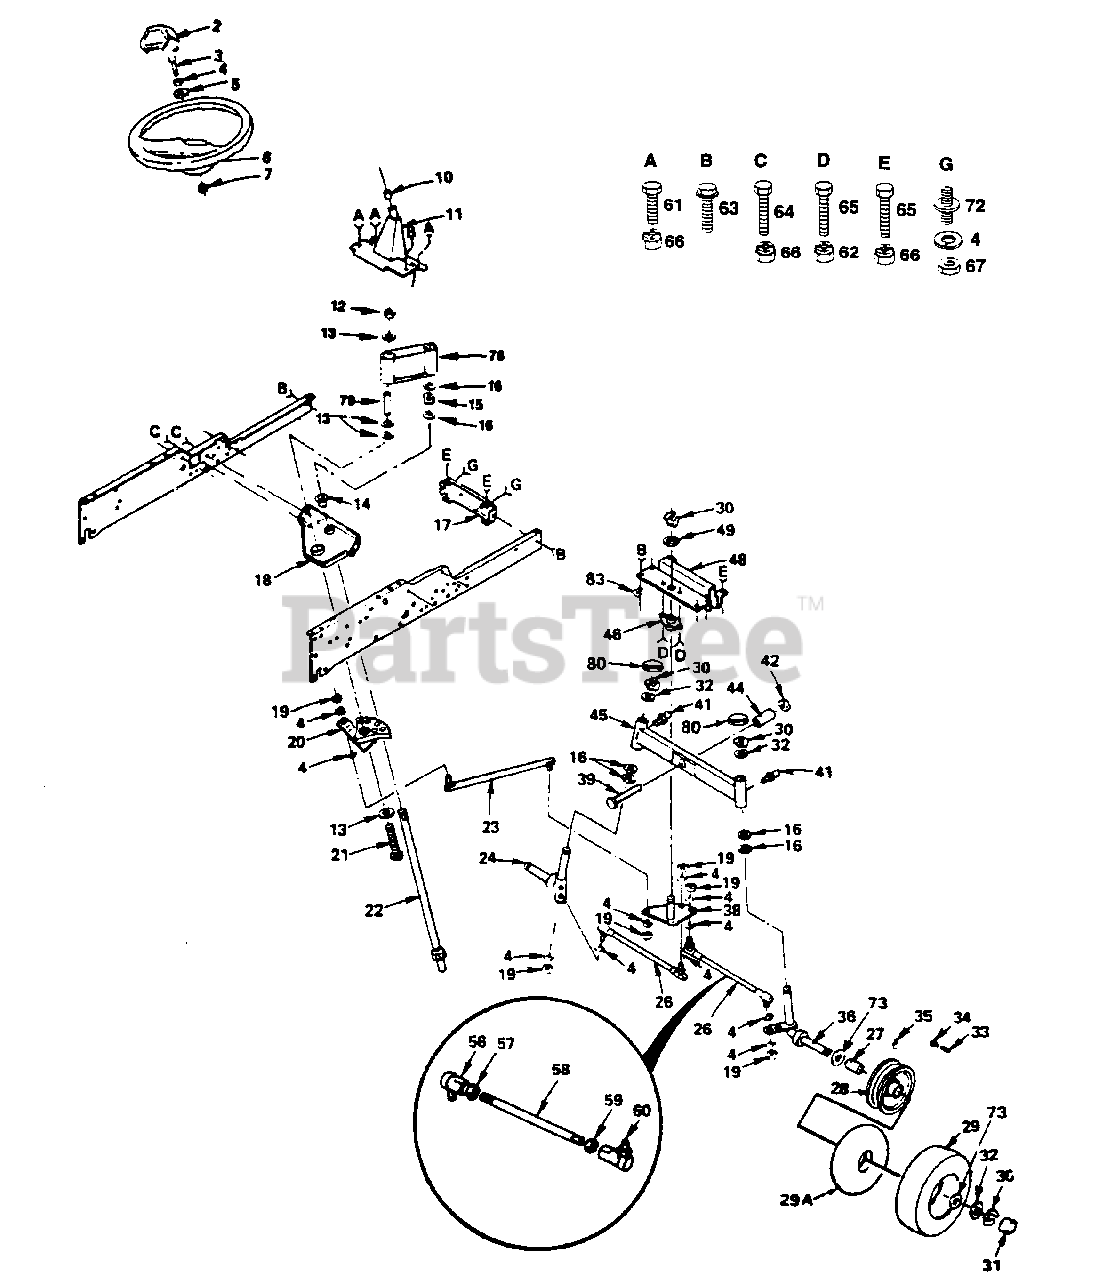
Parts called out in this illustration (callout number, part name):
2	Cap, Steering Wheel
3	Bolt, Hex 3/8-16 x 1 Grade 5
4	Washer, Lock 3/8
5	Washer 13/32 x 2-3/8 x 8 Gauge
6	Wheel, Steering
7	Adapter, Steering
10	Bearing
11	Support Assembly, Dash
12	Nut, Crownlock 1/2-13
13	Washer 17/32 x 1-5/8 x 10 Gauge
14	Bearing, Flanged
16	Bearing, Thrust
17	Bracket, Frame Front
18	Bracket, Support, Steering
19	Nut, Hex 3/8-24
20	Sector Assembly
21	Bolt, Hex 1/2-13 x 5 Grade 5
22	Shaft, Steering
23	Link, Drag
24	Spindle, L.H.
26	Rod, Tie (Inc. Key #56-60)
27	Bearing
28	Rim Assembly
29	Tire
29A	Tube (Optional, Service Item Only)
32	Washer 25/32 x 1-5/8 x 16 Gauge
35	Fitting, Grease
36	Spindle, R.H.
38	Bellcrank Assembly
39	Bolt, Hex 5/8-11 x 2-3/4 Grade 5
41	Fitting, Grease
42	Nut, Crownlock
44	Spacer Bearing
45	Axle Assembly, Front
46	Bushing, Bellcrank
48	Bracket, Axle
49	Washer 29/32 x 1-1/4 x 16 Gauge
56	Joint, Tie Rod, L.H. Thread
57	Nut, Hex Jam 3/8-24 L.H.
58	Rod, Tie
59	Nut, Hex Jam 3/8-24
60	Joint, Tie Rod, R.H. Thread
61	Bolt, Hex 3/8-16 x 3/4
62	Nut, Crownlock 3/8-16
63	Screw, Hex Washer Thd. Rolling 3/8-16 x 3/4
64	Bolt, Hex 3/8-16 x 1 Grade 5
65	Bolt, Hex 3/8-16 x 1
66	Nut, Lock Hex w/Ins 3/8-16
67	Nut, Hex 3/8-16
72	Pin Mounting, Idler Bracket
73	Washer 25/32 x 1-1/4 x 16 Gauge
76	Collar Weld Assembly
80	Dust Cap Cover
